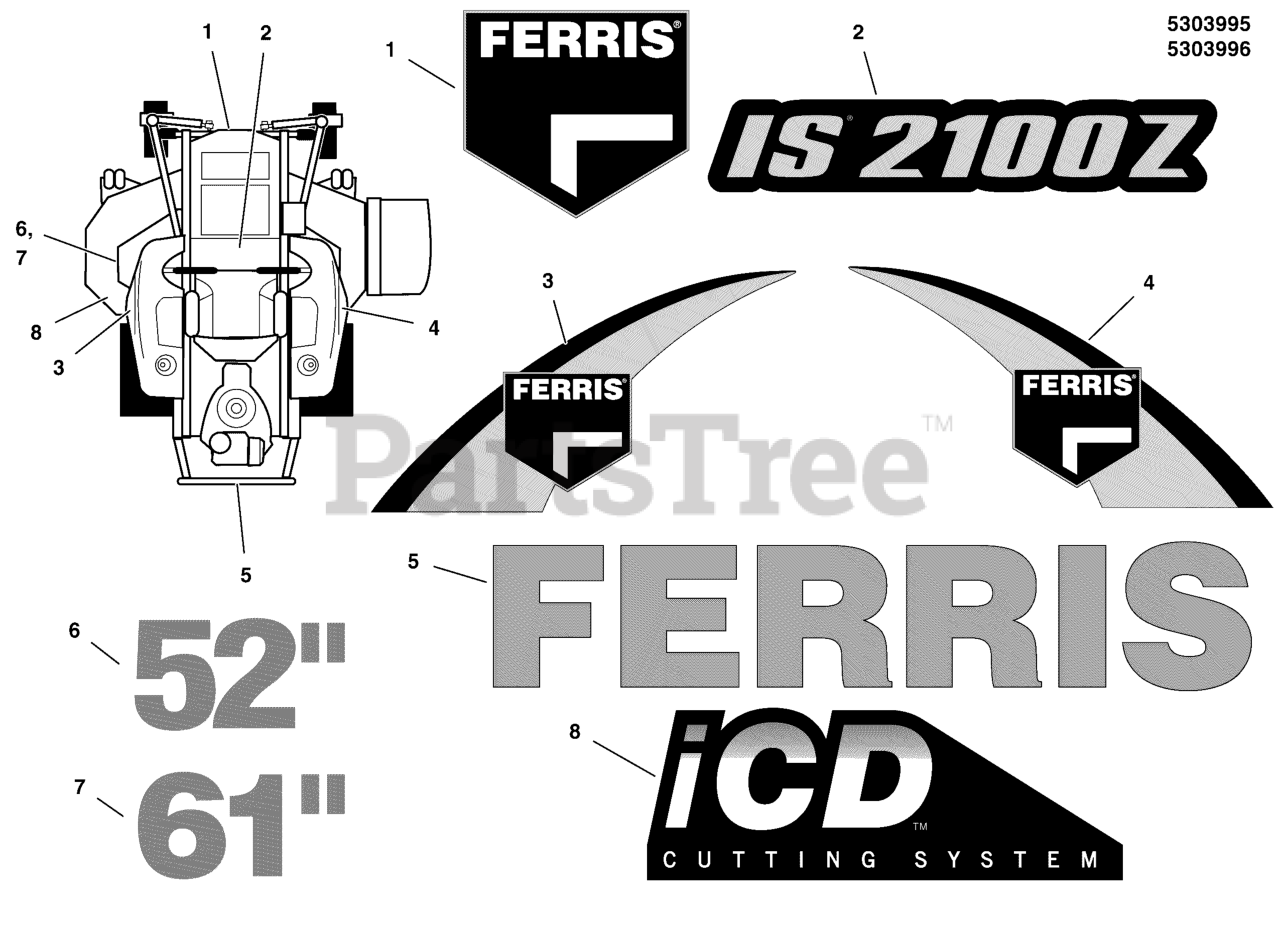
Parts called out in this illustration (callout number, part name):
1	DECAL, BRAND
2	DECAL, MODEL
3	DECAL, Model, Left Hand
4	DECAL, Model, Right Hand
5	DECAL, FERRIS, 2.23" X 11.39"
6	DECAL, 52
7	DECAL, 61
8	DECAL, iCD CUTTING SYSTEM
